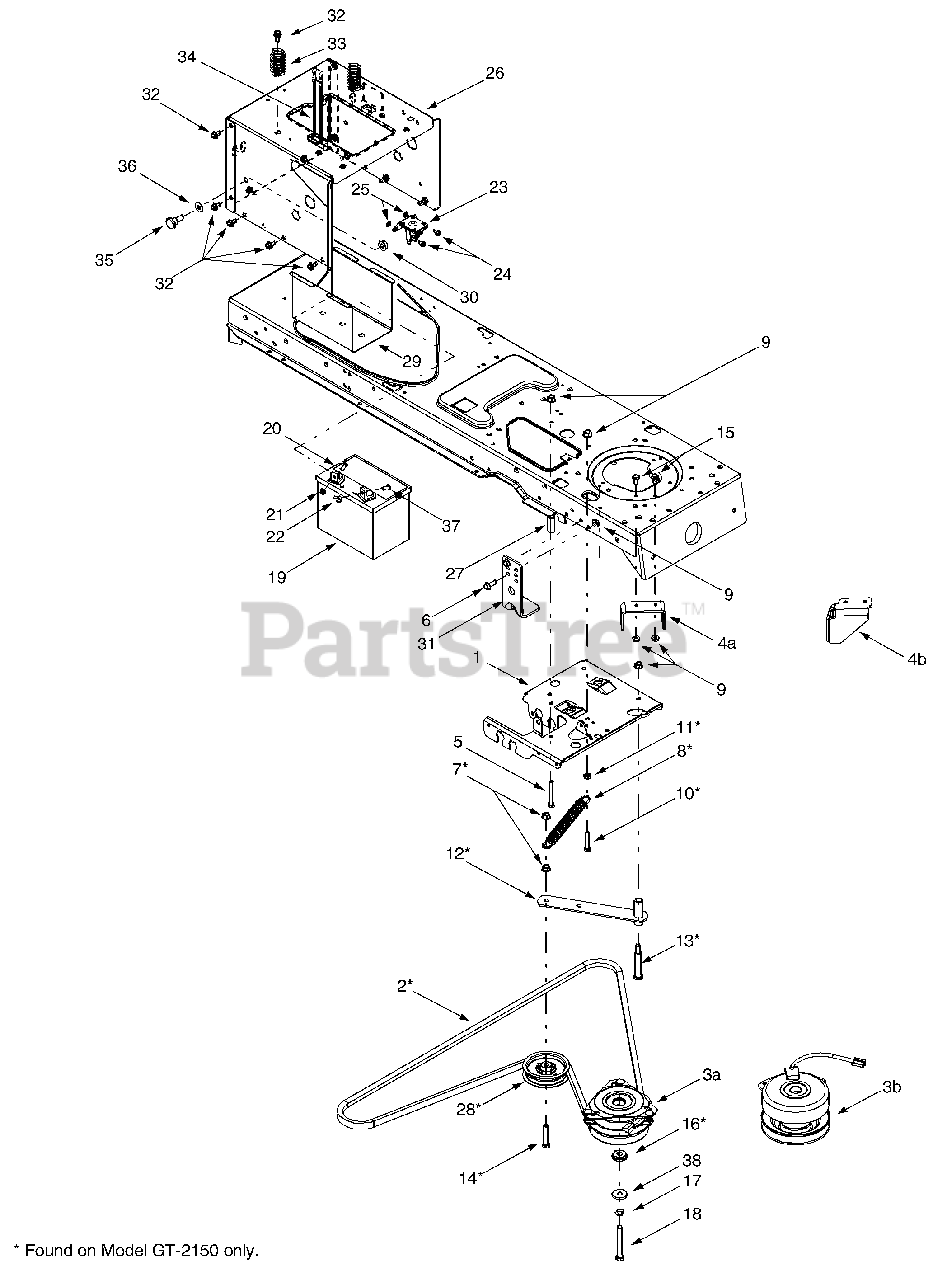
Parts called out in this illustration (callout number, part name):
2	PTO Belt
3A	Electric PTO Clutch (Model GT-2150)
3B	Electric PTO Clutch (Model GT-2550)
3B	Washer, Flat, 1.031 x 1.620 x .095
6	Hex Head Washer Screw, 5/16-18 x .875
7	Flange Lock Nut, 3/8-16
8	Extension Spring, .62 x 5.62
9	Flange Lock Nut, 5/16-18
10	Hex Cap Screw, 5/16-18 x 1.75
11	Hex Nut, 5/16-18
14	Hex Cap Screw, 3/8-16 x 2.0
15	Hex Cap Screw, 5/16-18 x .625
16	Shoulder Spacer, 1.38 x .445 x .36
17	Lock Washer, 7/16
18	Hex Cap Screw, 7/16-20 x 3.25 (Grade 5)
19	12-volt Battery, 270 CCA
20	Hex Cap Screw, 1/4-20 x .62
21	Hex Sems Nut, 1/4-20
22	Wing Nut, 1/4-20
23	Solenoid, 12-Volt, 100 Amp
24	Self Tapping Screw, 1/4-20 x .5
25	Lock Washer, 1/4
28	Idler Pulley, 3.5
32	Self Tapping Screw, 5/16-18 x .625
33	Compression Spring, 1.28 x 3.5
34	Battery Strap
35	Shoulder Screw, .625 x .5, 7/16-20
36	Bell Washer, .45 x 1.0 x .062
37	Shoulder Screw, 1/4-20, .25 x .15
38	Flat Washer, .45 x 1.25 x .164
